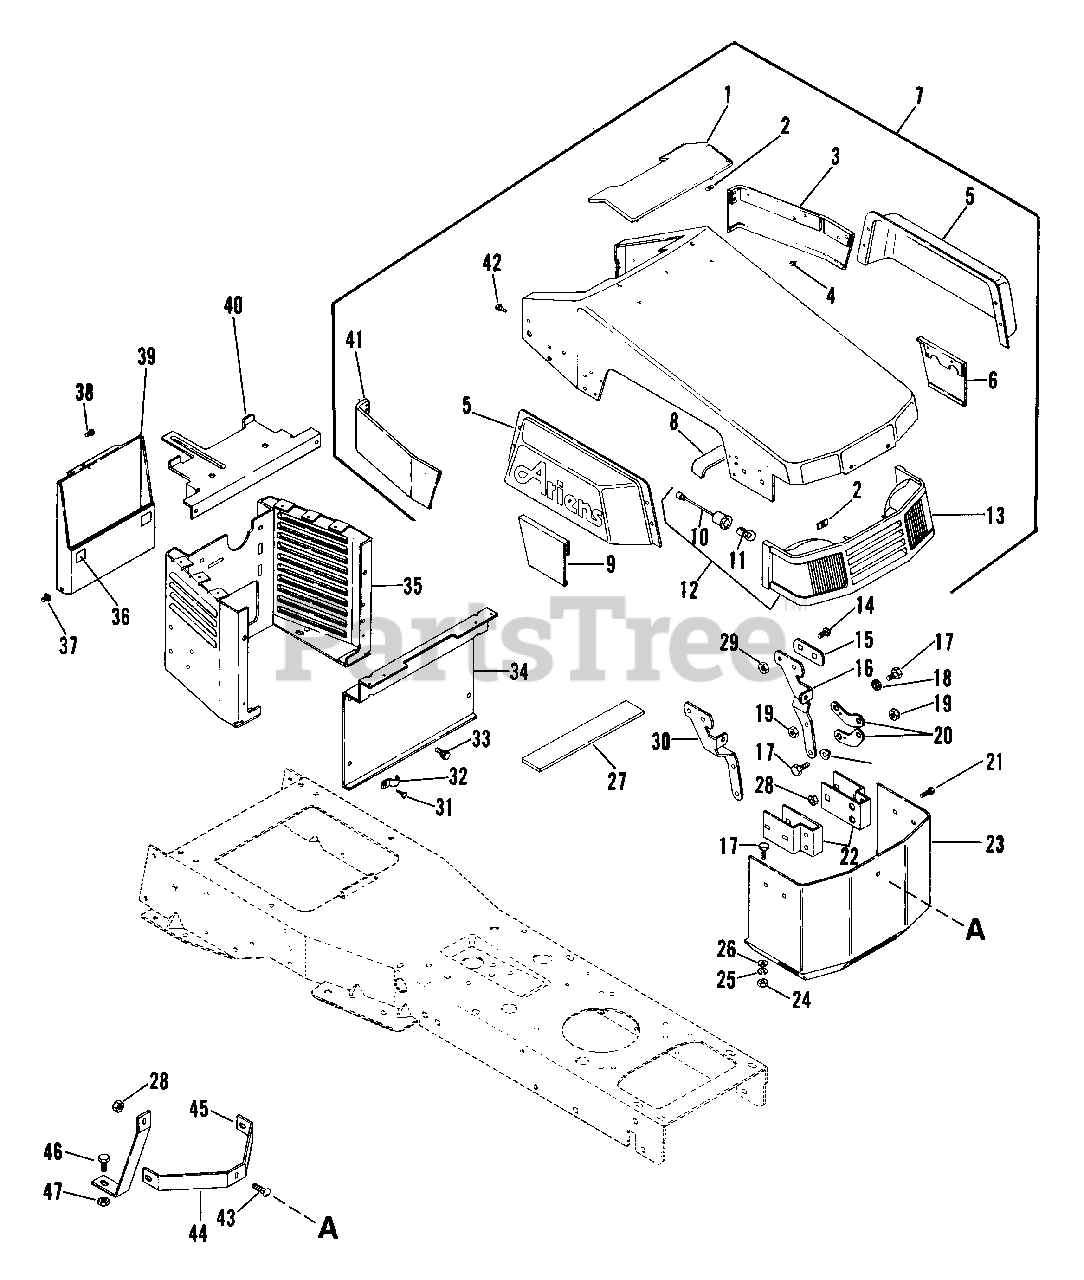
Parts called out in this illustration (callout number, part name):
1	HAND HOLD TRIM
2	NUT-SELF-THRDNG FITS.25 STUDPL
3	REAR HOOD MOLDING L H
4	RVT-BRIV .153 X .179 DOME AL
5	ENGINE SHROUD
6	FRONT HOOD MOLDING L H
7	HOOD ASSEMBLY
8	FOAM TAPE
9	FRONT HOOD MOLDING R H
10	SOCKET & HARNESS
11	HEADLIGHT BULB, 1156
12	HEAD LIGHT SYSTEM
13	GRILL & LENS ASSEMBLY
14	BLT-RDHDSQNK .31-18X.75 GR5 PL
15	SPACER STRAP
16	HINGE ARM L H
17	BLT-HEX .31-18X.75 PL GR2
18	BSHG, FLG .325X.499X.26X.88
19	NUT-LK .312-18 GR A PL
21	BLT-RDHDSQNK .25-20X.50 SHT PL
22	HINGE BRACKET
23	GRILL
24	NUT-HEX .312-18
25	WSHR-LK .312X.097 PL HVY
26	WSHR-FL-STL .323X.625X.062 PL
27	FOAM GASKET
28	NUT-LK-FLG .250-20 PL
29	NUT-FLG. .312-18 PL
30	HINGE ARM R H
31	SCR-TAP 10-16X.50 HWH PL AB
32	HOSE CLAMP
33	SCR-TAP .312-18X.50 HWH PL TR
34	BULKHEAD
35	DASH TOWER
36	CATCH ASSEMBLY
37	PLASTIC GROMMET
38	SCR-TAP 10-12X.50 CRPH PL A
39	NOTE BOX
40	BATTERY SUPPORT
41	REAR HOOD MOLDING R H
43	BLT-RDHDSQNK .25-20X.75 GR5PL
44	BRACE
45	BRACE
46	BLT-RDHDSQNK .375-16X.75 GR5PL
47	NUT-LK-FLG .375-16 PL
